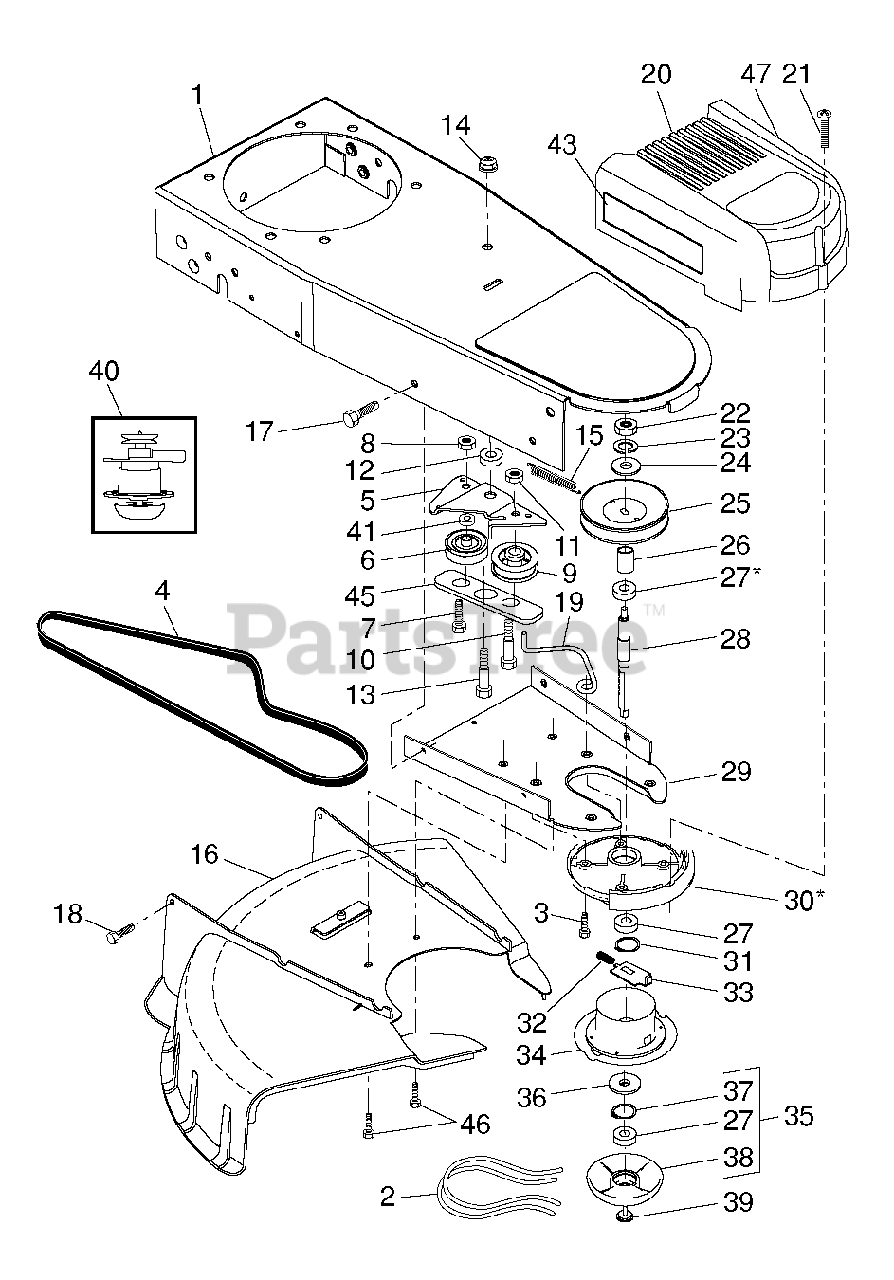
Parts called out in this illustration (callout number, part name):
2	LINE.BUND.18PC
4	BELT-V.STRING TRIMMER.
5	Idler Trimmer Wheel Bracket, 14
6	PULLEY.V-GROOVE.IDLER
7	BOLT, HEX HEAD 3/8-16 X 1.25
8	LOCKNUT
9	IDLER PULLEY
11	NUT.CENTERLOCK.5/16-
12	SPACER.IDLER.BRACKET
13	BOLT SHOULDER 3/8 -16X1
14	NUT.HEX.FLANGE.3/8-16.LOCKNUT
15	SPRING.RETURN.WHEELED.TRIMMER
16	Trimmer Deflector, Bottom HW
17	SCREW 14-20 X 5/8
19	BELT KEEPER
21	SCREW.SLOT.TORX.
22	NUT
23	LOCKWASHER
24	WASHER, FLAT 3/8
25	PULLEY.SPINDLE.WHEELED.TRIMMER
26	SPACER, PULLEY
27	BEARING
28	JACKSHAFT.WHEELED.TRIMMER
29	COVER, CHASSIS, BOTTOM
30	SPINDLE HOUSING ASSEMBLY
31	RING, RETAINING, EXTERNAL,
32	SPRING.1.5".COMPRESSION
33	LOCKING PLATE
34	CARRIER PLATE ASSEMBLY
35	MOW BALL ASSEMBLY
36	COVER, BEARING
37	RING, RETAINING, INTERNAL,
38	MOW BALL
39	BOLT, MOW BALL
40	ASM.ADJUSTABLE.SPINDLE.WHLD.TR
43	DECAL, INSTRUCTION
45	BRACKET.BELT.KEEPER.BLACK
47	DECAL.INSTRUCTION.CE.TRIM.STRG
